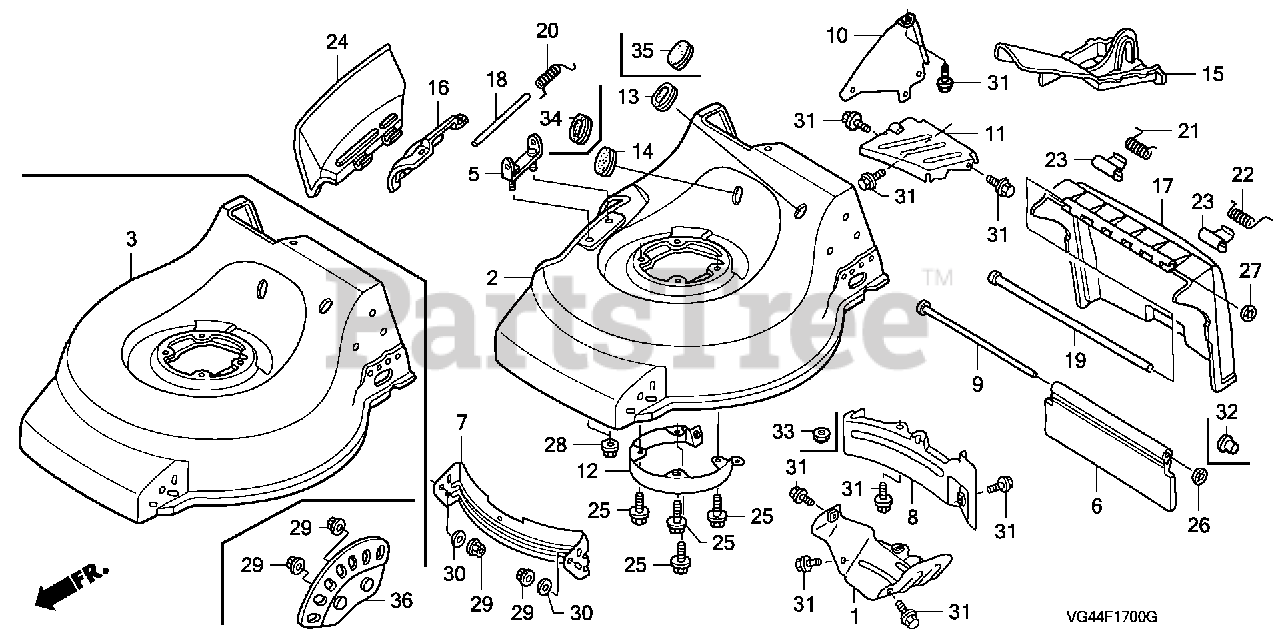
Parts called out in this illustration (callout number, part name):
1	COVER, BELT
2	HOUSING, CUTTER *NH190M* (VINTAGE GRAY METALLIC)
5	HINGE, DISCHARGE GUARD
6	SHIELD, RR.
7	SCROLL, FR.
8	SCROLL, RR.
9	SHAFT, RR. SHIELD (403MM) (NOT AVAILABLE)
9	SHAFT, RR. SHIELD (405MM)
10	PLATE, SCROLL
11	PLATE, GUIDE
12	COVER, ROTO-STOP
13	GROMMET, CABLE (HOLE)
14	GROMMET, PLUG
15	STUFFING *NH105* (MAT BLACK)
15	STUFFING *NH1* (BLACK)
16	GUARD, DISCHARGE *NH105* (MAT BLACK)
17	GUARD, DISCHARGE *NH105* (MAT BLACK)
18	SHAFT, DISCHARGE GUARD
19	SHAFT, DISCHARGE GUARD
20	SPRING, GUARD RETURN
21	SPRING, R. GUARD RETURN
22	SPRING, L. GUARD RETURN
23	PLATE, HINGE
24	CHUTE, SIDE DISCHARGE *NH105* (MAT BLACK)
25	BOLT, FLANGE (5/16-24X1")
26	NUT, PUSH (3.96MM) (FLAT ROUND TYPE) (NOT AVAILABLE)
27	NUT, PUSH (7.94MM)
28	NUT, FLANGE (6MM)
29	NUT, FLANGE (8MM)
30	WASHER, PLAIN (5/16)
31	BOLT, FLANGE (6X10)
32	NUT, PUSH (3.96MM) (CAPPED TYPE)
32	NUT, PUSH (3.96MM) (FLAT ROUND TYPE)
